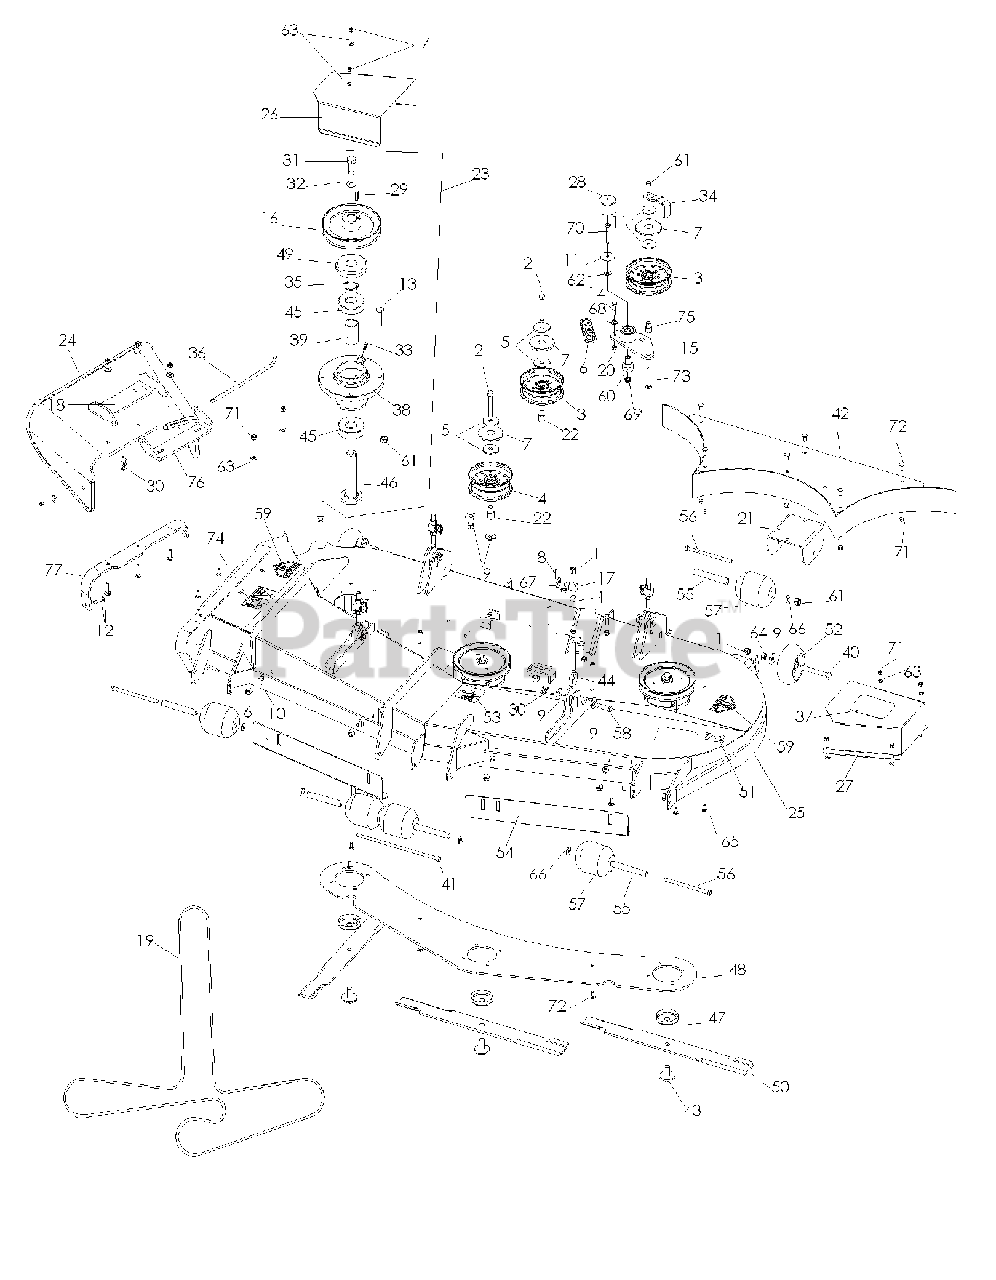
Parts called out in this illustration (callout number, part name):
1	NUT 1/2-13 HEX NYLOC ZD
2	SCREW, 1/2C X 3 HEX CAP
3	IDLER PULLEY
4	IDLER PULLEY (TALL)
5	ISOLATOR WASHER
6	DECK SPRING
7	TOP DUST CAP
8	PIN COTTER 1/8 X 1 ZD
9	WASH USS FLAT 1/2
10	RHSNB 3/8-16 X 3/4 GR5 ZD
11	WASHER, 3/8 SPEC
12	RHSNB 5/16-18 X 1-1/2 GR 5 ZD
13	HCS 3/8C X 1 1/2
14	HCS 3/8-16 X 1-1/2
15	ARM-IDLER W/BRG
16	PULLEY, 7.50 O.D.
18	PIVOT BRKT RUBBER CHUTE
19	BELT-DECK, 72
20	NUT 3/8-16 HEX JAM
21	REAR CENTER ROLLER BKT 72 BLK
22	SPACER - IDLER
23	SPINDLE ASSEMBLY, 72
24	CHUTE, RUBBER DISCHARGE 72"
25	DECK W/DECAL 72 GRIZZLY
26	PULLEY GUARD 72, RH PAINTED
27	PULLEY GUARD 72, LH PAINTED
28	CAP, VINYL
29	KEY - 1/4 X .88
30	PIN, COTTER 1 3/4
31	1/2-20 UNF X 1 1/4 HHBLT
32	WASHER .525 X 1.375 X .25
33	ZERK, 3/16, DRIVE IN
34	GUIDE, BELT
35	SPACER .25
36	DEFLECTOR PIN
37	REAR FLOOR PAD-LH
38	DECK HUB MACHINED
40	HCS 1/2-13 X 4 GR 5 ZD
41	3/8-16X12 HHB G5
42	W-BAFFLE WLDT
43	BLADE BOLT/WASHER
44	BOLT, EYE
45	BEARING - 6305 - 2RS
46	SHAFT SHORT
47	TRASH GUARD
48	HUB STIFFENER PLATE
49	TRASH GUARD
50	BLD 72" HI LIFT FUS
51	DECAL, 72"
52	GAUGE WHEEL
53	DECAL, BELT ROUTING (18656)
54	BLOW BY BAFFLE
55	BUSHING
56	3/8-16 X 6-1/2 HHB GR8
57	ROLLER 3-3/4 DIA. X 4-1
58	CLEVIS PIN 1/2X1-3/4LG
59	DECAL, CPSC
60	PIVOT, BEARING
61	NUT 3/8-16 NYLOC
62	WASHER 3/8 SAE FLAT
63	FLAT WASHER 5/16 SAE
64	NUT HEX 1/2
65	BOLT 5/16C X 3/4" CARRIAGE
66	WASHER 3/8 FLAT
67	WASHER 1/2 FLAT
68	HCS 3/8C X 1
69	NUT 3/8C WHIZ
70	HCS 3/8C X 2 1/2
71	NUT 5/16 NYLOC
72	RHSSNB 5/16C X 1.0
73	RHSNB 3/8-16 X 2.75
74	DECAL, EURO SEVERING
75	BUSHING, IDLER
76	PIVOT BRACKET - DECK
77	BRKT, REINF-CHUTE 72"
